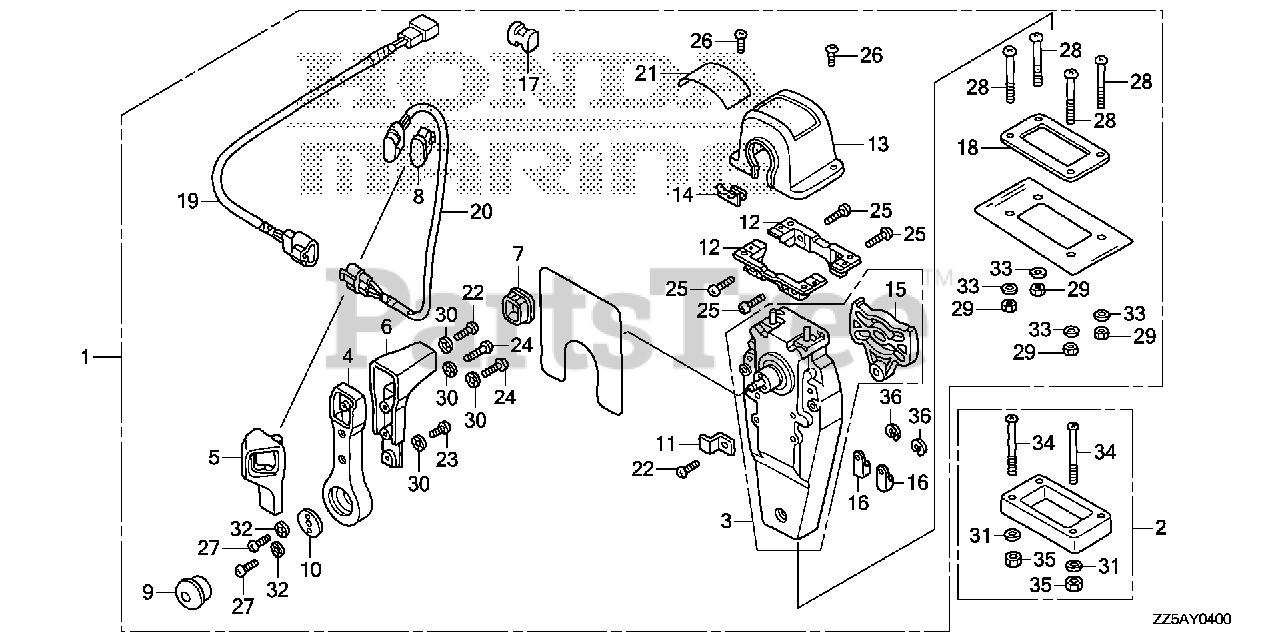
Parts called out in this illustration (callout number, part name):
1	BOX KIT, REMOTE CONTROL (TOP MOUNT SINGLE)(R)
2	SPACER KIT, REMOTE CONTROL BOX (TOP MOUNT SINGLE)
3	HOUSING ASSY., L. (INNER) (TOP MOUNT)
4	HANDLE, REMOTE CONTROL
5	COVER, L. GRIP
6	GRIP, REMOTE CONTROL HANDLE
7	CAP, GRIP
8	CAP, SWITCH
9	BUTTON, THROTTLE
10	PLATE, HANDLE
11	PLATE, CABLE CLAMP
12	BRACKET, REMOTE CONTROL HOUSING
13	HOUSING, REMOTE CONTROL BOX
14	HOUSING, LEAD
15	PLATE, DWELL
16	TERMINAL, CABLE
17	SPACER, CABLE CLAMP
18	GASKET, SINGLE
19	SUB-HARNESS ASSY., POWER TRIM-TILT (A)
20	SWITCH ASSY., POWER TRIM-TILT (A)
21	MARK, REMOTE CONTROL (SINGLE)
22	SCREW, PAN (5X16)
23	SCREW, PAN (5X10)
24	SCREW, PAN (5X20)
25	SCREW, PAN (5X18)
26	SCREW, PAN (4X10)
27	SCREW, PAN (6X18)
28	SCREW, PAN (5X40)
29	NUT, HEX. (5MM)
30	WASHER, LOCK (5MM)
31	WASHER, PLAIN (5MM)
32	WASHER, LOCK (6MM)
33	WASHER, PLAIN (5MM)
34	SCREW, PAN (5X65)
35	NUT, HEX. (5MM)
36	E-RING (6MM)
